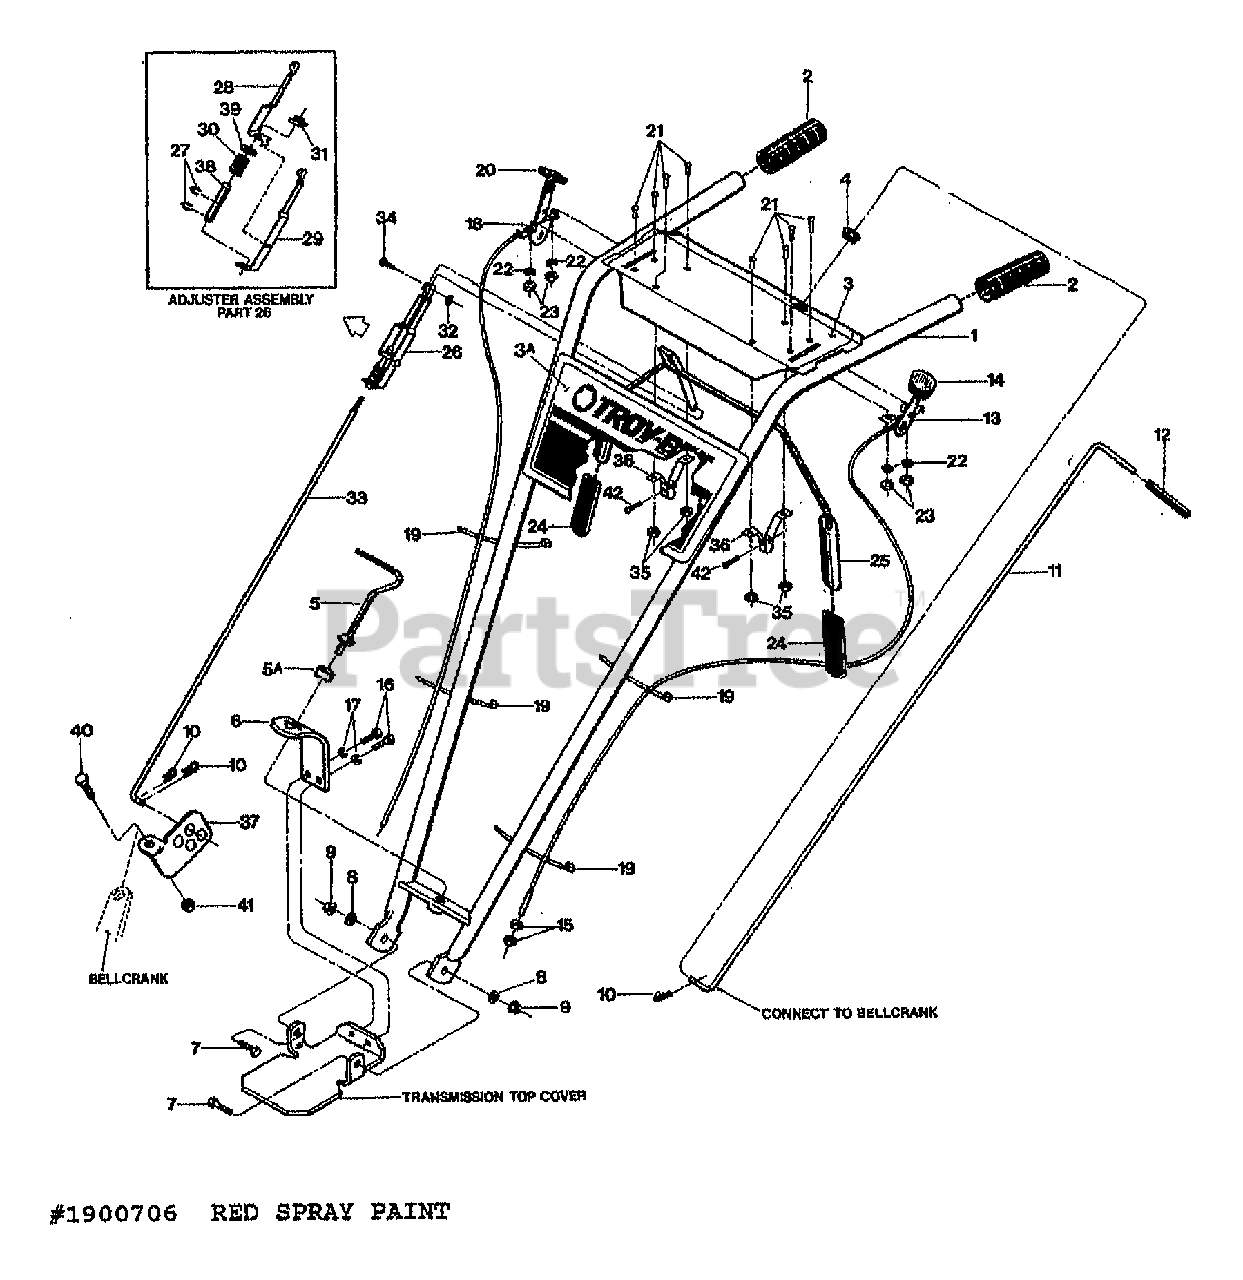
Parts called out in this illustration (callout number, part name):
1	ASSM-HANDLEBAR W/GRIPS (INCL. 2,3,3A,4)
2	GRIP-H/B 1" PONY/P-J OPC
3	DECAL-CONTROL PANEL
3A	DECAL-GRAPHICS PANEL PONY
4	BUSHING-NYLON (PART OF OPERATOR CONTROL PANEL)
5	ASSM-STUD H/B
5A	WASHER-1.0X.38X.375
6	PLATE-HANDLEBAR ADJUST
7	SCR-HH 3/8-16X1.0 G5 ZP (USED TO ATTACH HANDLEBARS TO TABS ON TRANS. TOP COVER)
8	WASHER-FLAT 3/8 SAE (HANDLEBAR ATTACHMENT)
9	NUT-LOCK 3/8-16 NYLON ZP (HANDLEBAR ATTACHMENT)
10	PIN-CLIP .08
11	ROD-REV W/GRIP OPC (INCL. #9198)
12	GRIP-CONTROL ROD
13	CABLE-WHEEL CLUTCH OPC (INCL. 14,15,19,21-23)
14	KNOB-WHEEL DRIVE CABLE
15	NUT-HEX 5/16-24
16	SCR-HH 3/8-16X.75 G5 ZP
17	WASHER-LK .375 @ DEPL
18	CABLE-THROTTLE PONY OPC
19	TIE-RED (TO SECURE CABLES TO HANDLEBARS)
20	KNOB-THROTTLE CABLE
21	SCR-RH M10-32X.5 MACH
22	WASHER-LK M10
23	NUT-HH M10-32X.125
24	GRIP-PADDLE SM FRAME OPC
25	BAIL W/GRIPS OPC (INCL. TWO #24)
26	ASSM-ADJUSTMENT OPC (INCL. 27-30, 38-39)
27	RING-KLIP .500 ZINC
28	ADJUSTER-RT SIDE OPC
29	ADJUSTER-LT SIDE OPC
30	SPRING-ADJUSTER OPC
31	WELDNUT 5/16-18
32	RING-KLIP .188 DIA
33	ROD-CONTROL OPC
34	ASSM-PIN & CLIP (SMALL FRAME)
35	NUT W/LKWASHER #10-32 ZP
36	BRACKET-BAIL OPC
37	SWIVEL-SMALL FRAME
38	BUSHING-.5X.334X2.88
39	WASHER-.75X.51X.06 ZP
40	SCR-HH 1/4-20X.75 G5 ZP
41	NUT-LK 1/4-20
42	SCR-HWH 1/4-20 X .5 STH
